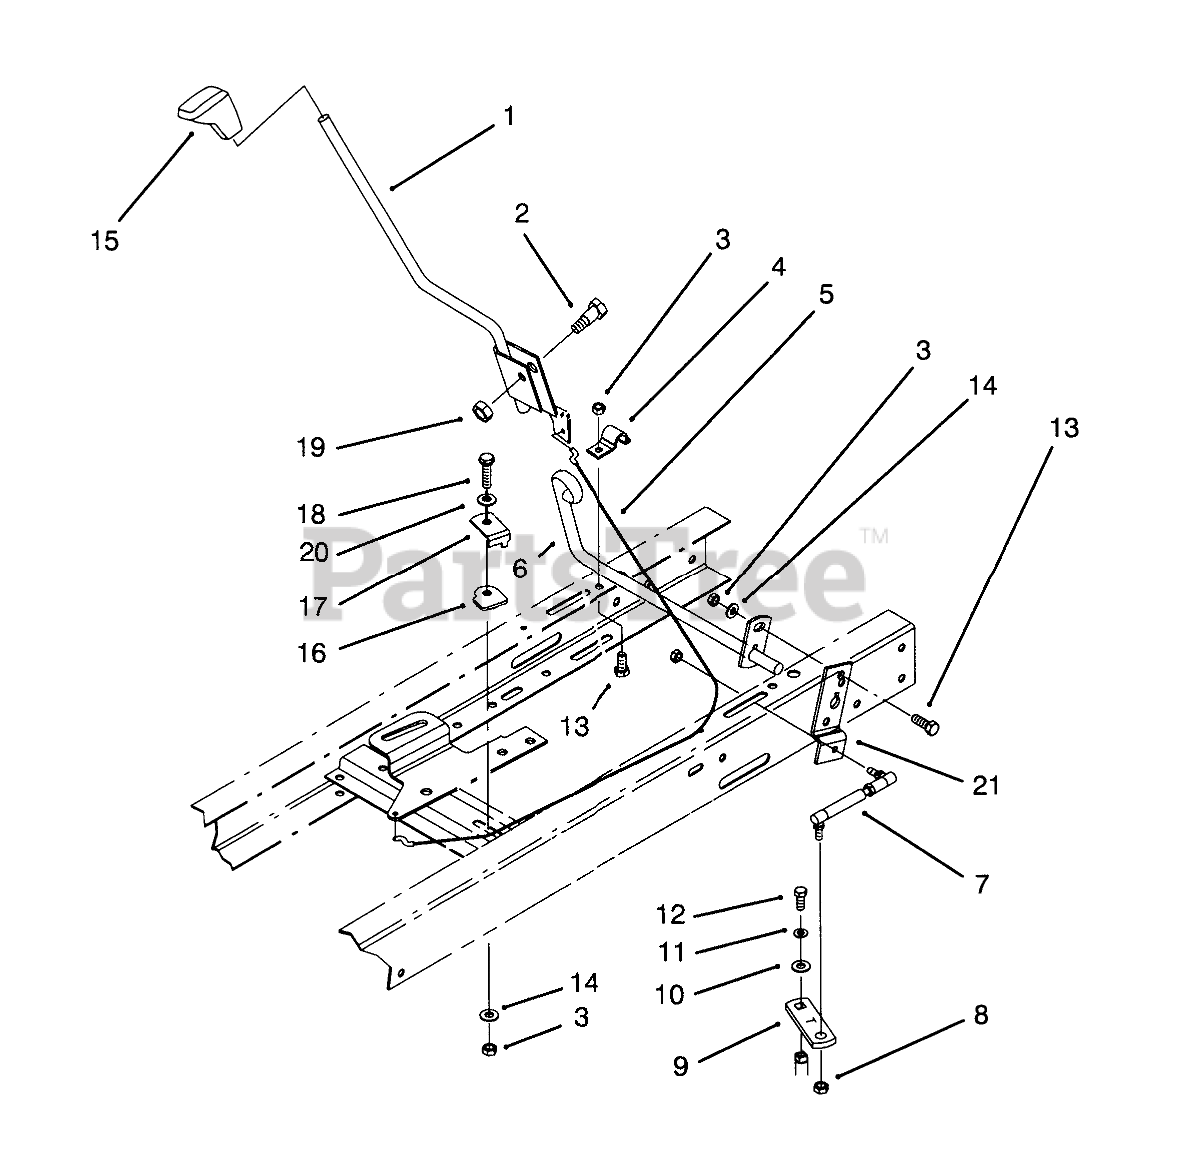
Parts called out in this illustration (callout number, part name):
1	Lever-Shift
2	SHOULDER BOLT
3	NUT-LOCK, NI
4	CLAMP-PIVOT, SHIFT
5	CABLE-CLUTCH
6	SHIFT PIVOT WAB
7	TIE ROD, SHIFT
8	NUT-LOCK
9	LEVER-SHIFT
10	SPACER
11	WASHER-LOCK
12	SCREW-HH
13	SCREW-HH
14	WASHER-PLAIN
15	SHIFT KNOB
16	GUIDE-CABLE
17	KEEPER-CABLE
18	SCREW-CARR
19	NUT-LOCK, NI
20	WASHER-FLAT
21	SHIFT LEVER PIVOTB
